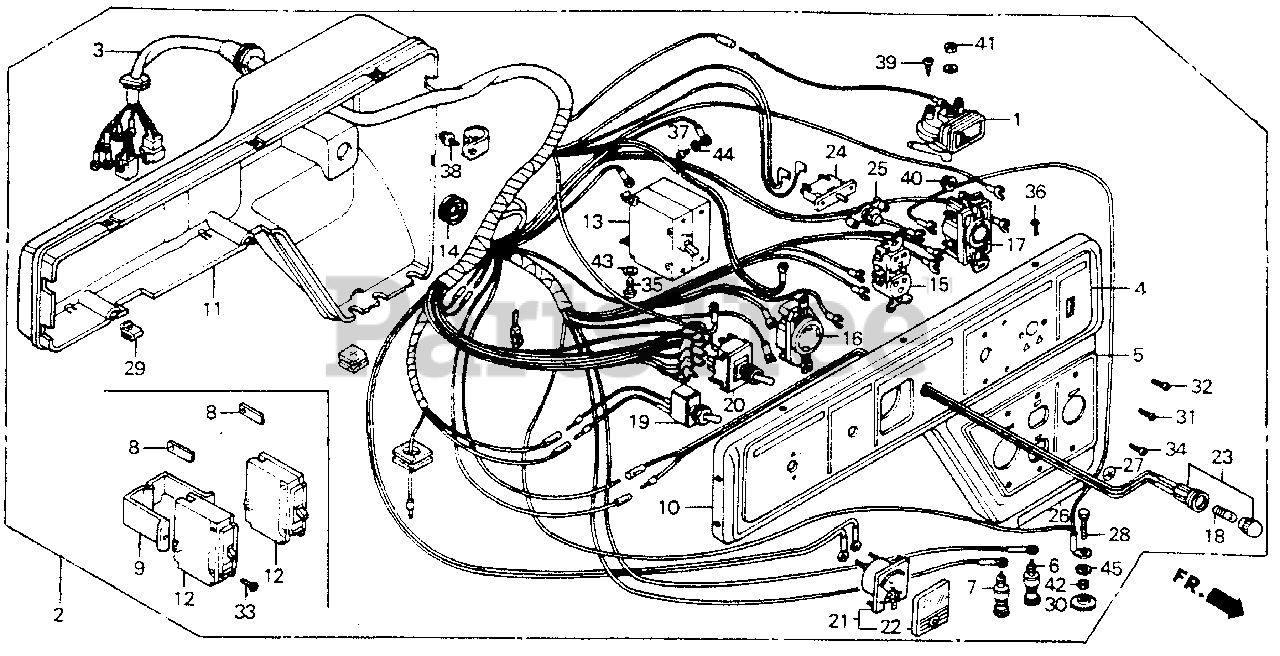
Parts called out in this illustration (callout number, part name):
1	SWITCH ASSY., UNIT
2	BOX ASSY., CONTROL *R8* (BRIGHT RED)
2	BOX ASSY., CONTROL *R8* (BRIGHT RED) (NOT AVAILABLE)
3	WIRE HARNESS ASSY.
3	WIRE HARNESS ASSY. (NOT AVAILABLE)
4	MARK, SWITCH PANEL
5	MARK, A.C. OUTPUT
5	MARK, A.C. OUTPUT (NOT AVAILABLE)
6	TERMINAL, D.C. OUT (+)
7	TERMINAL, D.C. OUT (-)
8	TERMINAL, BREAKER
9	SUPPORT, BREAKER (NOT AVAILABLE)
10	PANEL, CONTROL *R8* (EM-A) (BRIGHT RED)
10	PANEL, CONTROL *R8* (BRIGHT RED) (NOT AVAILABLE)
11	CASE, CONTROL (NOT AVAILABLE)
12	BREAKER, CIRCUIT (17A)
13	BREAKER, CIRCUIT (17A) (NOT AVAILABLE)
14	GROMMET, UNIT SWITCH
15	RECEPTACLE ASSY. (125V-20A)
15	RECEPTACLE (20A/125V)
16	RECEPTACLE (3-PRONG) (30A/125V)
17	RECEPTACLE (20A/125-250V)
18	BULB (24V2W)
19	SWITCH ASSY., ENGINE (NOT AVAILABLE)
20	SWITCH ASSY., VOLT CHANGE
21	VOLTMETER ASSY.
22	LENS, METER
23	SOCKET ASSY., PILOT LAMP
24	PROTECTOR, CIRCUIT (DC)
25	LENS ASSY., PROTECTOR
26	MARK, D.C. OUTPUT (NOT AVAILABLE)
27	MARK, GROUND
28	BOLT, HEX. (6X18)
29	NUT, SPRING (5MM)
30	NUT, SPECIAL (6MM)
31	SCREW, PAN (3X6)
32	SCREW, PAN (3X12)
33	SCREW, PAN (4X6)
34	SCREW, PAN (4X8)
35	SCREW, PAN (4X10)
36	SCREW, PAN (5X12)
37	SCREW, PAN (5X12)
38	SCREW-WASHER (5X10)
39	SCREW, TAPPING (5X10)
40	NUT, HEX. (4MM)
41	NUT, HEX. (5MM)
42	NUT, HEX. (6MM)
43	WASHER, SPRING (4MM)
44	WASHER, SPRING (5MM)
45	WASHER, SPRING (6MM)
